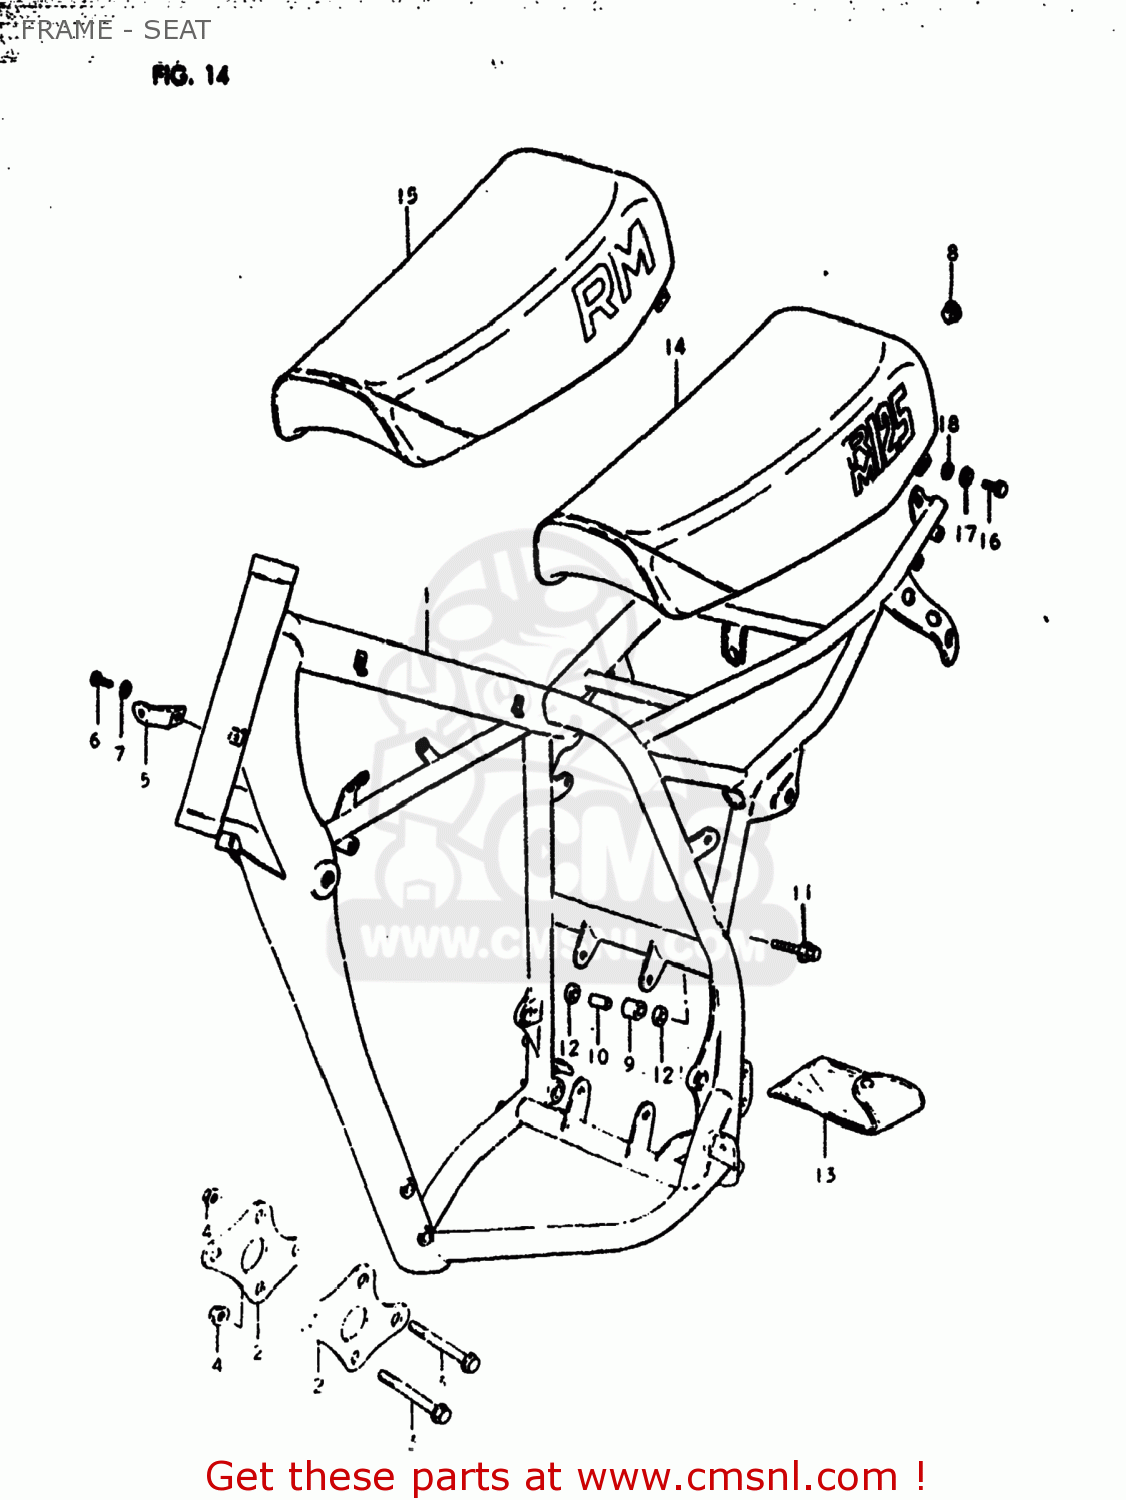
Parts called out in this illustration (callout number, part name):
1	FRAME
2	PLATE,ENGINE MOUNTING
3	BOLT(8X67)
4	NUT
5	PLATE,ENGINE MOUNTING
6	BOLT
7	LOCK WASHER
8	PLUG(OD:19)
9	ROLLER,CHAIN CONTROL
10	SPACER,CHAIN LENGTH ROLLER
11	BOLT(8X45)
12	WASHER
13	TOOL SET
14	SEAT ASSEMBLY
15	SEAT ASSEMBLY
16	BOLT, UPPER
17	LOCK WASHER
18	WASHER(6.5X18X1)
